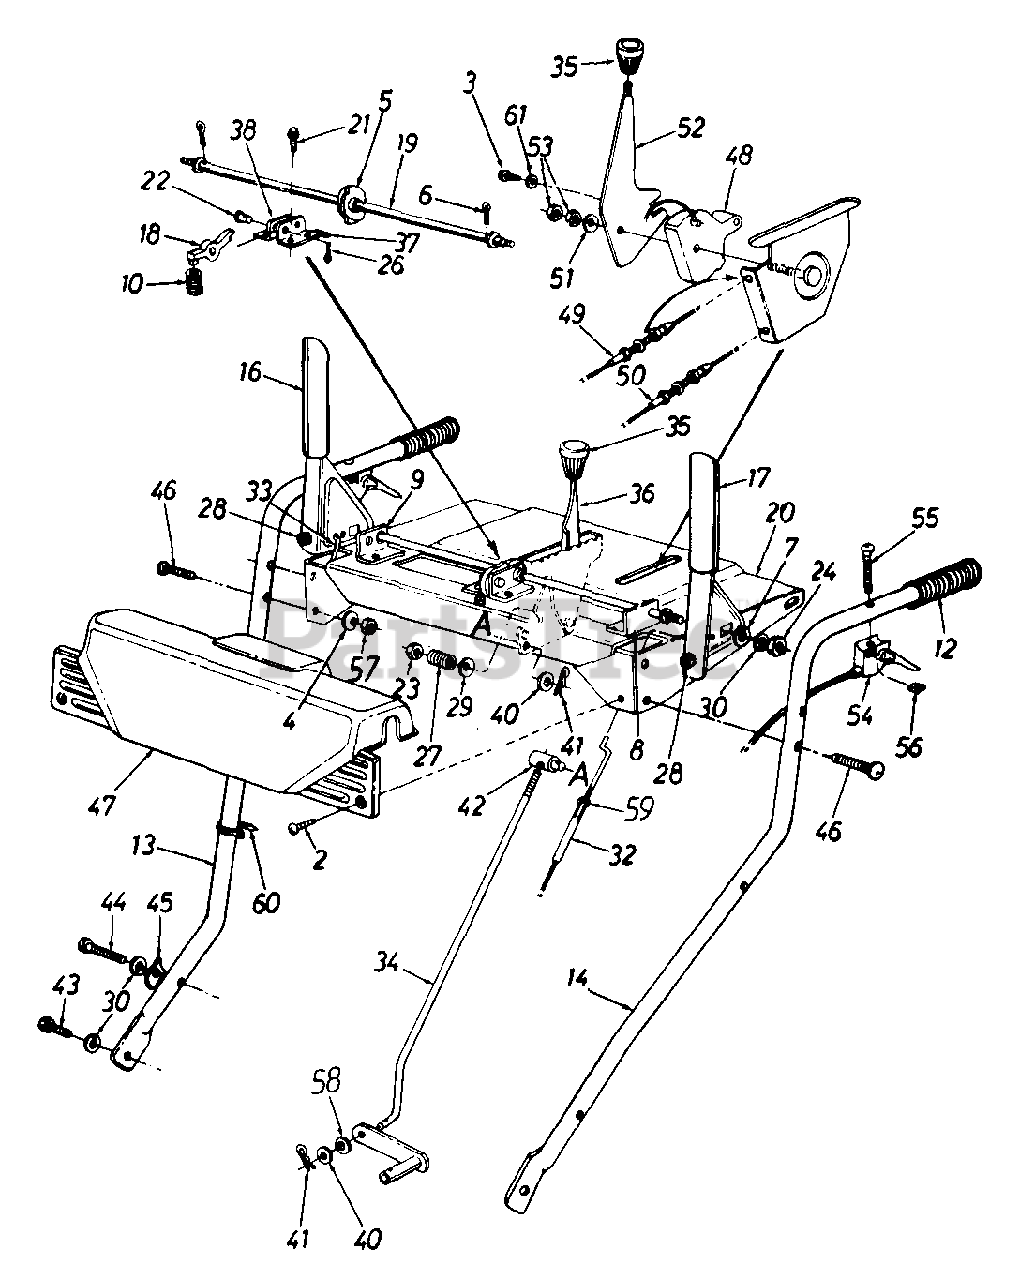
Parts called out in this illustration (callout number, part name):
2	Truss Mach. B-Tap Scr. #10 x .5
3	Hex AB-Tap Scr. 1/4 x .62" Lg.
4	Bell-Wash. .325" I.D. x .88" O.D.
5	Cam Handle Lock
6	Cotter Pin 3/32" Dia. x .75" Lg.
7	Washer .72" O.D.
10	Compression Spring
13	Handle - R.H.
14	Handle - L.H.
16	Engagement Handle - R.H.
17	Engagement Handle - L.H.
18	Pawl Handle Lock
19	Rod Cam
22	Clevis Pin .437" Dia. x .65" Lg.
23	Hex Ins. L-Nut 3/8-24 Thd.
24	Hex Nut 5/16-18 Thd.
26	Cotter Pin 3/32" Dia. x 1" Lg.
27	Compression Spring
28	Rubber Bumper
29	Bell-Wash..38" I.0. x.88" O.D.
30	L-Wash. 5/16" I.D.
32	Auger Clutch Cable
33	Drive Clutch Cable
34	Shift Rod
35	Shift Knob
36	Shift Handle
40	Fl-Wash..344" I.D. x .62" O.D.
41	Internal Cotter Pin 5/16" Dia.
42	Ferrule
43	Hex Bolt 5/16-18 x .62" Lg.
44	Hex Bolt 5/16-18 x 1.75" Lg. (Gr. 5)
45	Handle Tab
46	Curved Carr. Bolt 5/16-18 x 1.5" Lg.
47	Handle Panel
48	Cable Guide
49	Chute Control Cable
50	Chute Control Cable w/Clip
51	Bell-Wash. .325" I.D. x .93" O.D.
53	Hex Cent. L-Nut 5/16-18 Thd.
54	Track Steer Cable w/Trigger
55	Oval C-Sunk Hd. Scr. 10-24 x 1.375" Lg.
56	Flat Weld Nut #10-24 Thd.
57	Hex Nut 5/16-18 Thd.
58	Spr. Wash. .32" I.D. x .62" O.D.
59	Hex Nut #10-24 Thd.
60	Cable Tie
61	Washer 1.25" O.D.
